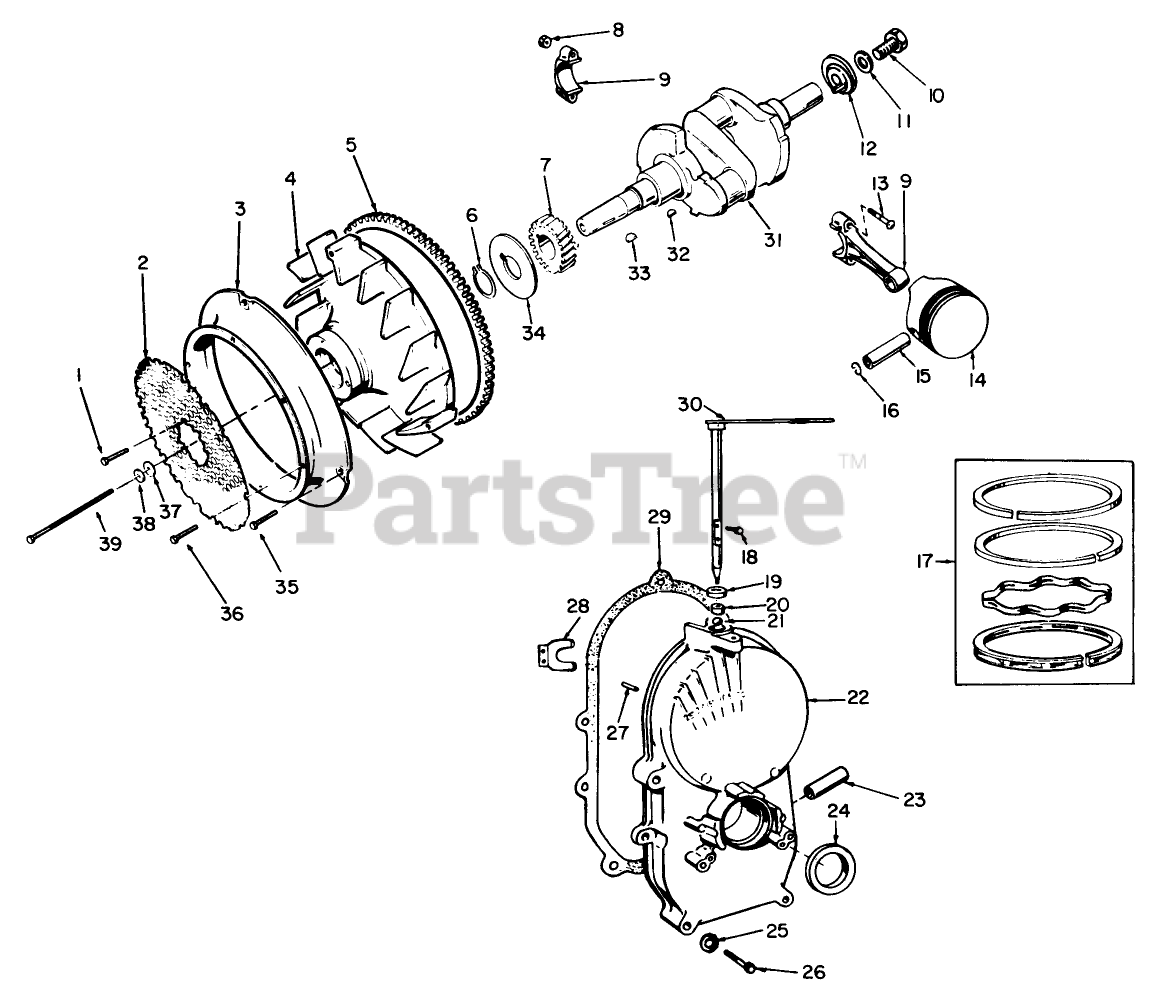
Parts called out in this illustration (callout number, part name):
1	Screw, Cap-Hex Head Locking
2	Guard, Flywheel
3	Venture, Blower Wheel
4	Flywheel (Incl. Ref. #5)
5	Gear, Ring
6	Ring Retaining
7	Gear Crankshaft
8	Nut, Hex-Crown Lock
9	Rod, Connecting-Standard (Incl. Ref. #8 13)
10	Screw, Cap Hex Hd.
11	Washer, Lock-Spring
12	SPACER
13	Bolt, Special-Connecting Rod
14	Piston and Pin-Standard (Incl. Ref. #15 16)
15	Pin, Piston
16	Ring, Retaining
17	Ring Set, Piston-Standard
18	Screw, Machine-Pan Hd.
19	Ball, Bearing-Governor Shaft
20	Bearing, Governor Shaft
21	Seal, Oil-Governor Shaft
22	Gear Case Assembly (Incl. Ref. #1 8-21, 23-24, 27-28 30)
23	Tube, Vacuum Port
24	Seal, Oil-Crankshaft
25	Washer, Flat Copper
26	Screw Cap Hex Hd.
27	Pin, Dowel-Governor Cup Stop
28	Yoke, Governor Shaft
29	Gasket, Gearcase Mounting
30	Shaft and Arm, Governor
31	STRIP-BULB
32	Key Crankshaft Gear
33	Key Flywheel
34	Washer, Gear Retaining
35	Screw Cap Hex Washer Hd.
36	Screw Tapping Hex Washer Hd.
37	Washer, Flat
38	Washer, Lock-Spring
39	Screw, Cap-Hex Head
